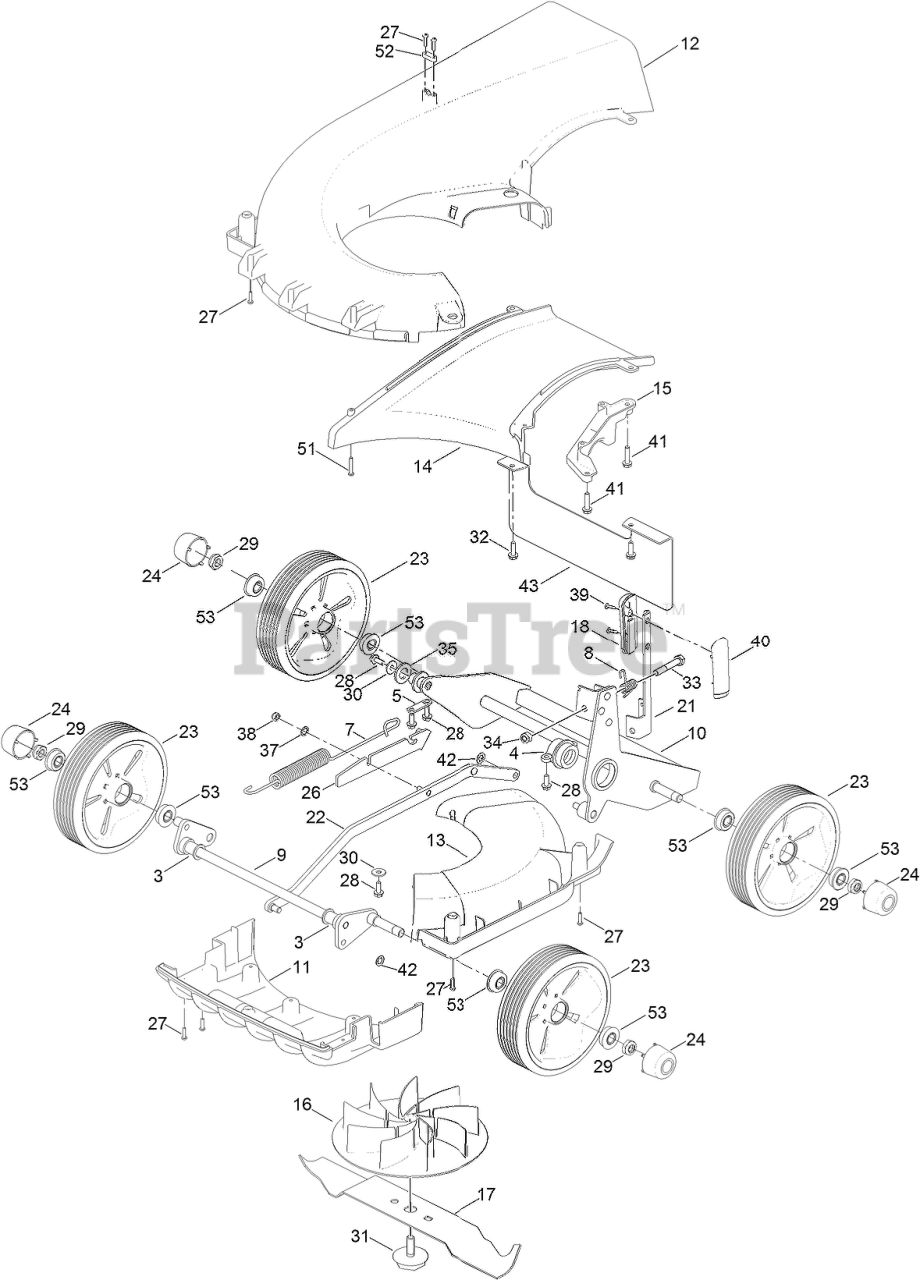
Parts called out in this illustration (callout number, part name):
3	BEARING-AXLE, FRONT
4	HOUSING-PIVOT BEARING, LH
5	PLATE-SECURING
7	SPRING-COUNTER BALANCE
8	SPRING-HOC
9	AXLE-FRONT
10	FRAME-WHEEL
11	MOULDING-FIN
12	MOULDING-SNAIL DECK
13	MOULDING-ACCESS, SNAIL DECK
14	MOULDING-THROW PLATE
15	MOUNT-BEARING
16	MOULDING-MOUNT, ELECTRIC BLADE
17	CUTTERBAR-ELECTRIC
18	KNOB-HOC, RH
21	LEVER-HOC
22	ROD-CONNECTING BAR
23	WHEEL ASM
24	CAP-WHEEL, CENTER
26	MOUNT-SPRING
28	SCREW-TAPTITE
29	NUT-NYLOC
30	WASHER
31	BOLT-FIXING, BLADE
32	SCREW-TAPTITE
34	NUT-HEX, NI
35	WASHER-PLAIN
37	WASHER-PLAIN
38	NUT-NYLOC
40	KNOB-HOC, LH
41	SCREW-HH
42	WASHER-STARLOCK
43	GUARD-REAR
52	CLAMP-CABLE
53	Bearing
